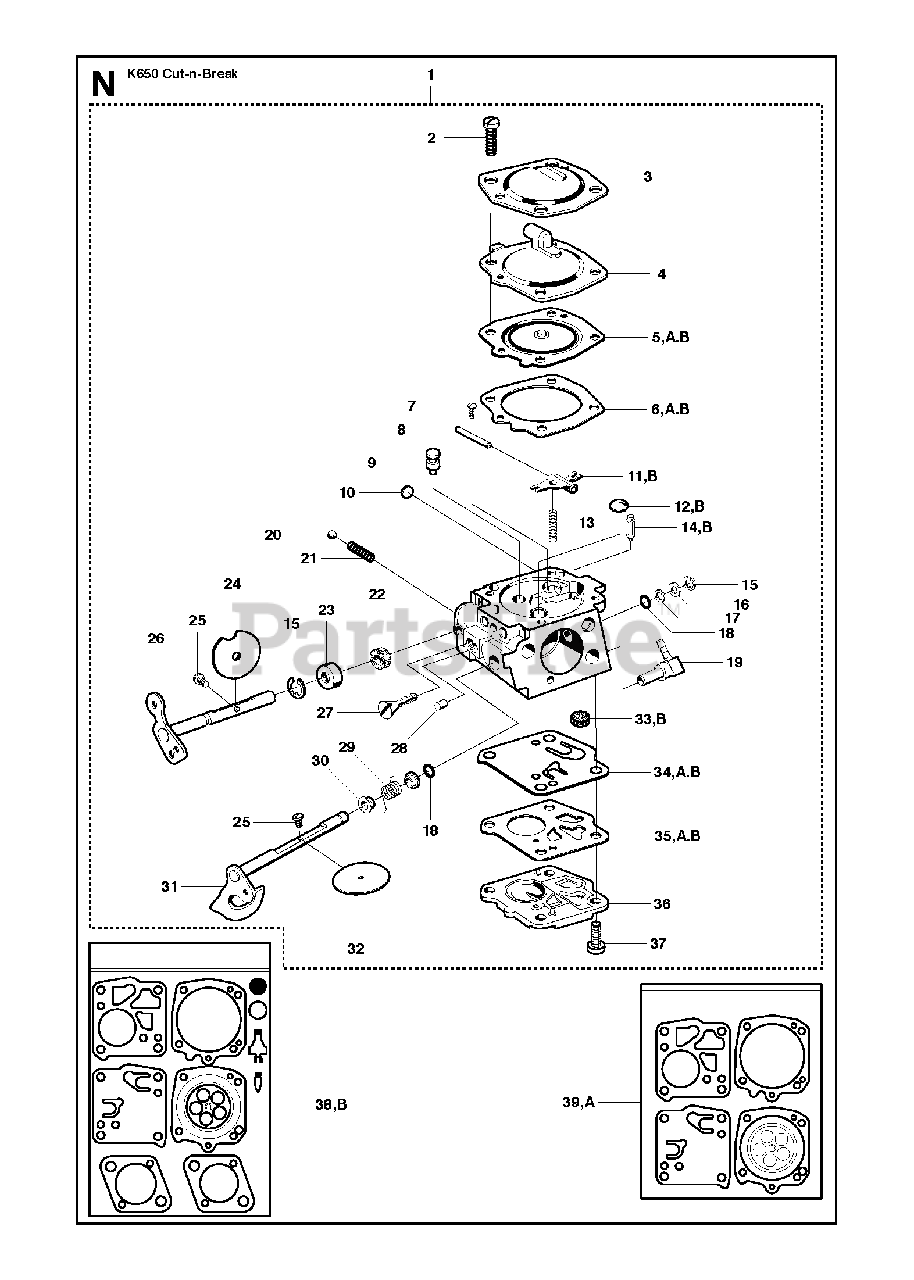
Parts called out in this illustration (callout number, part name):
1	CARBURETTORTillotson HS 175N. Incl. 2 - 39
5	DIAPHRAGMKit 38 & 39
6	DIAPHRAGMKit 38 & 39
7	PIN RETAINING SCREW
8	PIN RETAINING SCREW
9	CHECKVALVE ASSY
15	THROTTLE SH."E"RING
20	CHOKE FRICTION BALL
25	SCREW SHUTTER
27	IDLE SPEED SCREW
28	SPEED SCREW RET BALL
29	THROTTLE SH. SPRING
34	FUEL PUMP DIAPHRAMKit 38 & 39
35	FUEL PUMPKit 38 & 39
36	FUEL PUMP COVER
